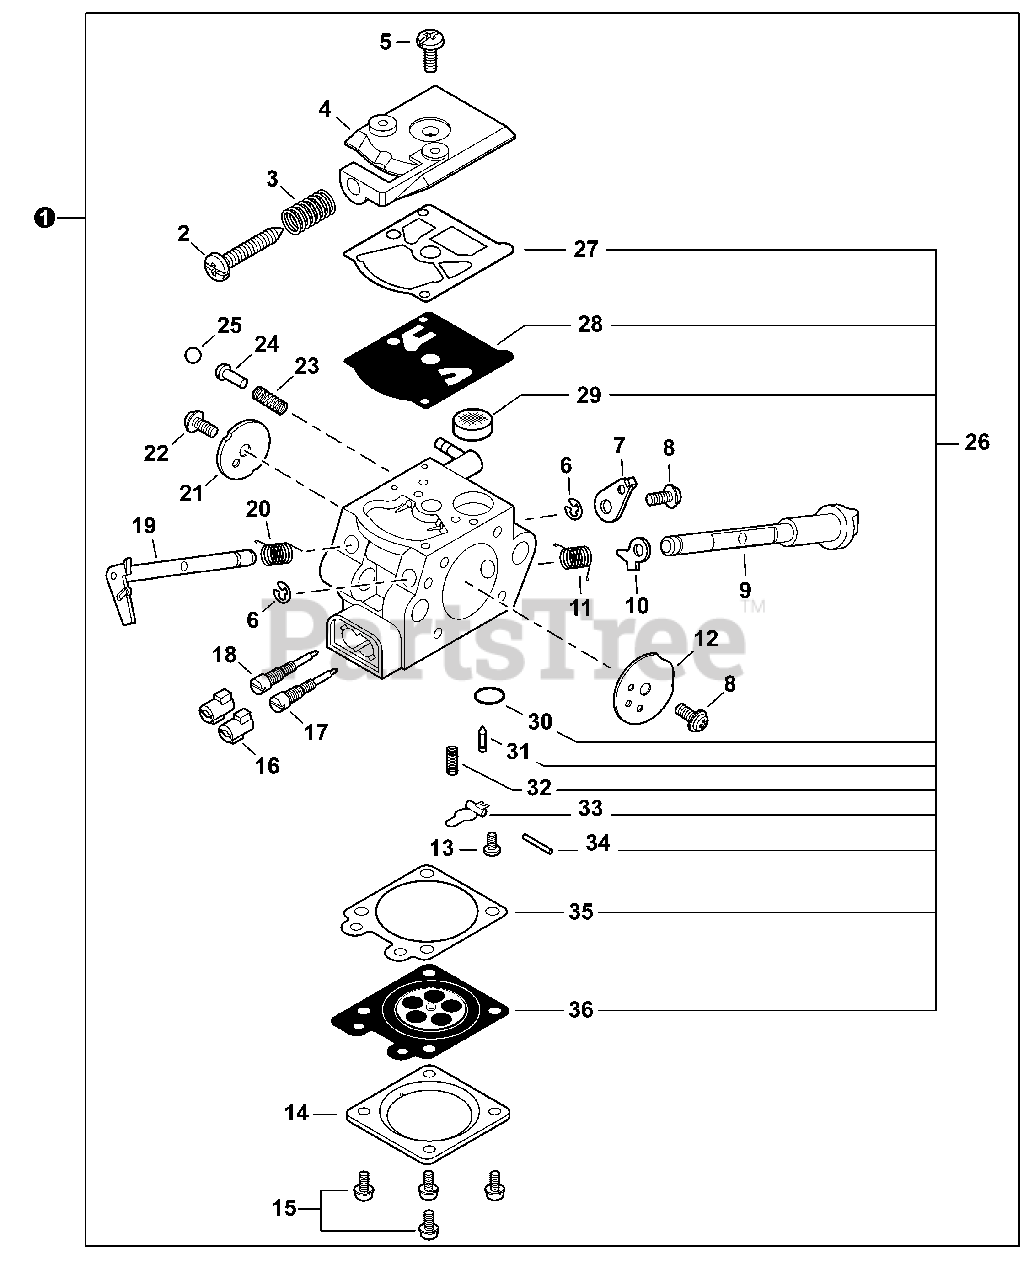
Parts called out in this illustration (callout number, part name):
1	CARBURETOR - WT-1008
2	SCREW, IDLE ADJUST
3	SPRING, IDLE ADJUST
4	COVER, PUMP
7	LEVER, THROTTLE
9	SHAFT ASSY, CHOKE
10	LEVER, FAST IDLE
12	VALVE, CHOKE
13	SCREW, METERING LEVER PIN
14	COVER, METERING DIAPHRAGM
16	CAP, LIMITER
17	NEEDLE, MIXTURE
18	NEEDLE, MIXTURE
19	SHAFT ASSY, THROTTLE
20	SPRING, THROTTLE RETURN
21	VALVE, THROTTLE
23	SPRING, START VALVE
24	PISTON ASSY
26	REPAIR KIT, CARBURETOR
27	GASKET, PUMP
28	DIAPHRAGM, PUMP
29	SCREEN, INLET
30	PLUG, WELCH
31	VALVE, INLET NEEDLE
32	SPRING, METERING LEVER
33	LEVER, METERING
34	PIN, METERING LEVER
35	GASKET, METERING DIAPHRAGM
36	DIAPHRAGM, METERING
